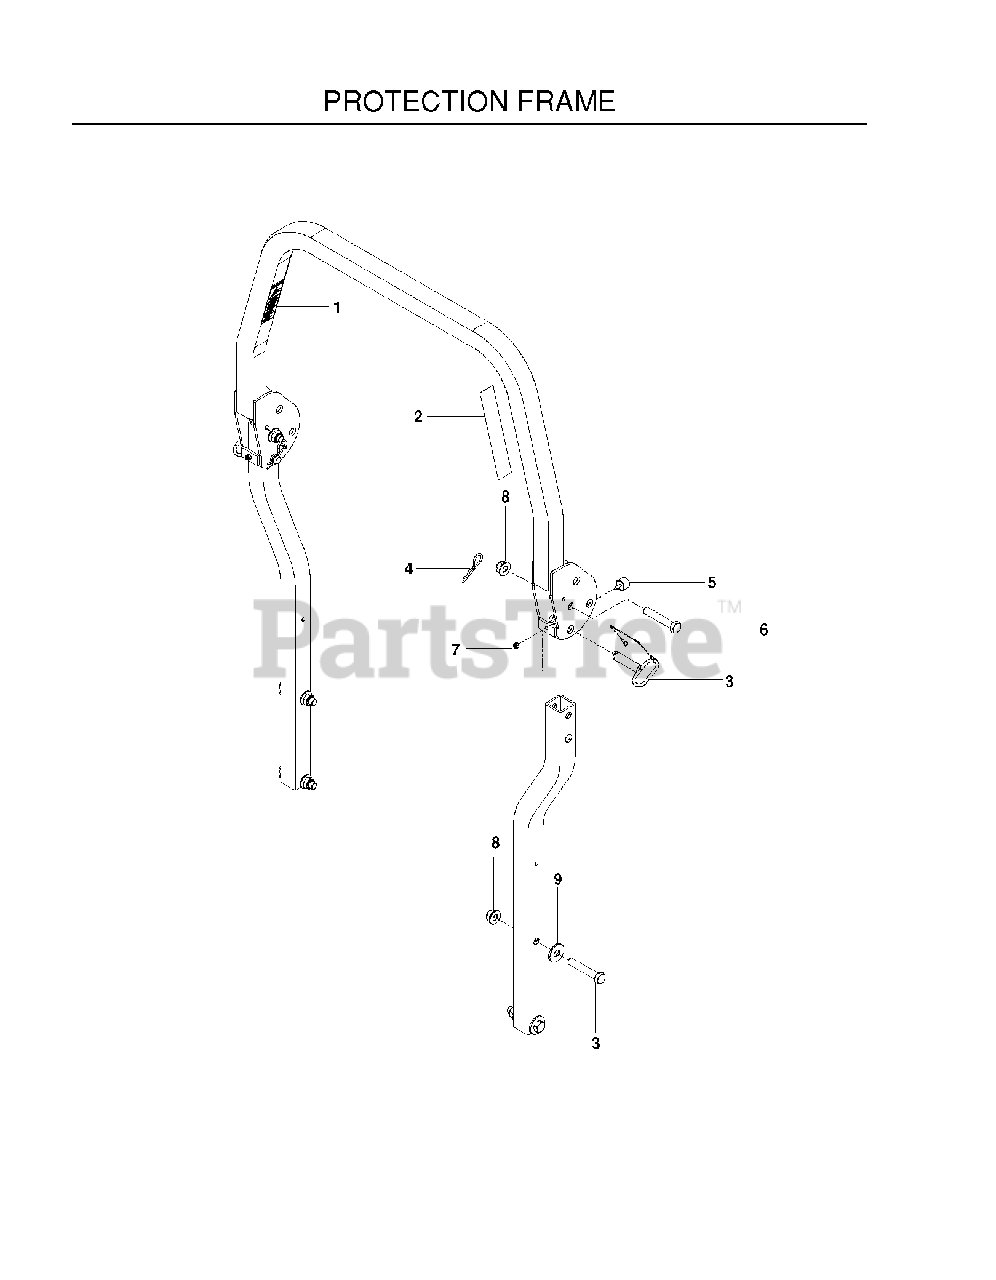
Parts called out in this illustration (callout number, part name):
1	DECAL, ROPS, WARNING
3	PIN, ROPS
4	PIN HAIR .148 X 2-15/16 #210
5	BUMPER, MALE STUD, 1/4-20
6	5/8-11 X 3-1/2 HHB
7	NUT 1/4-20 NYLOC
8	NUT 5/8-11 FLG NYLOC ZD
9	WASHER, 5/8 FLAT
